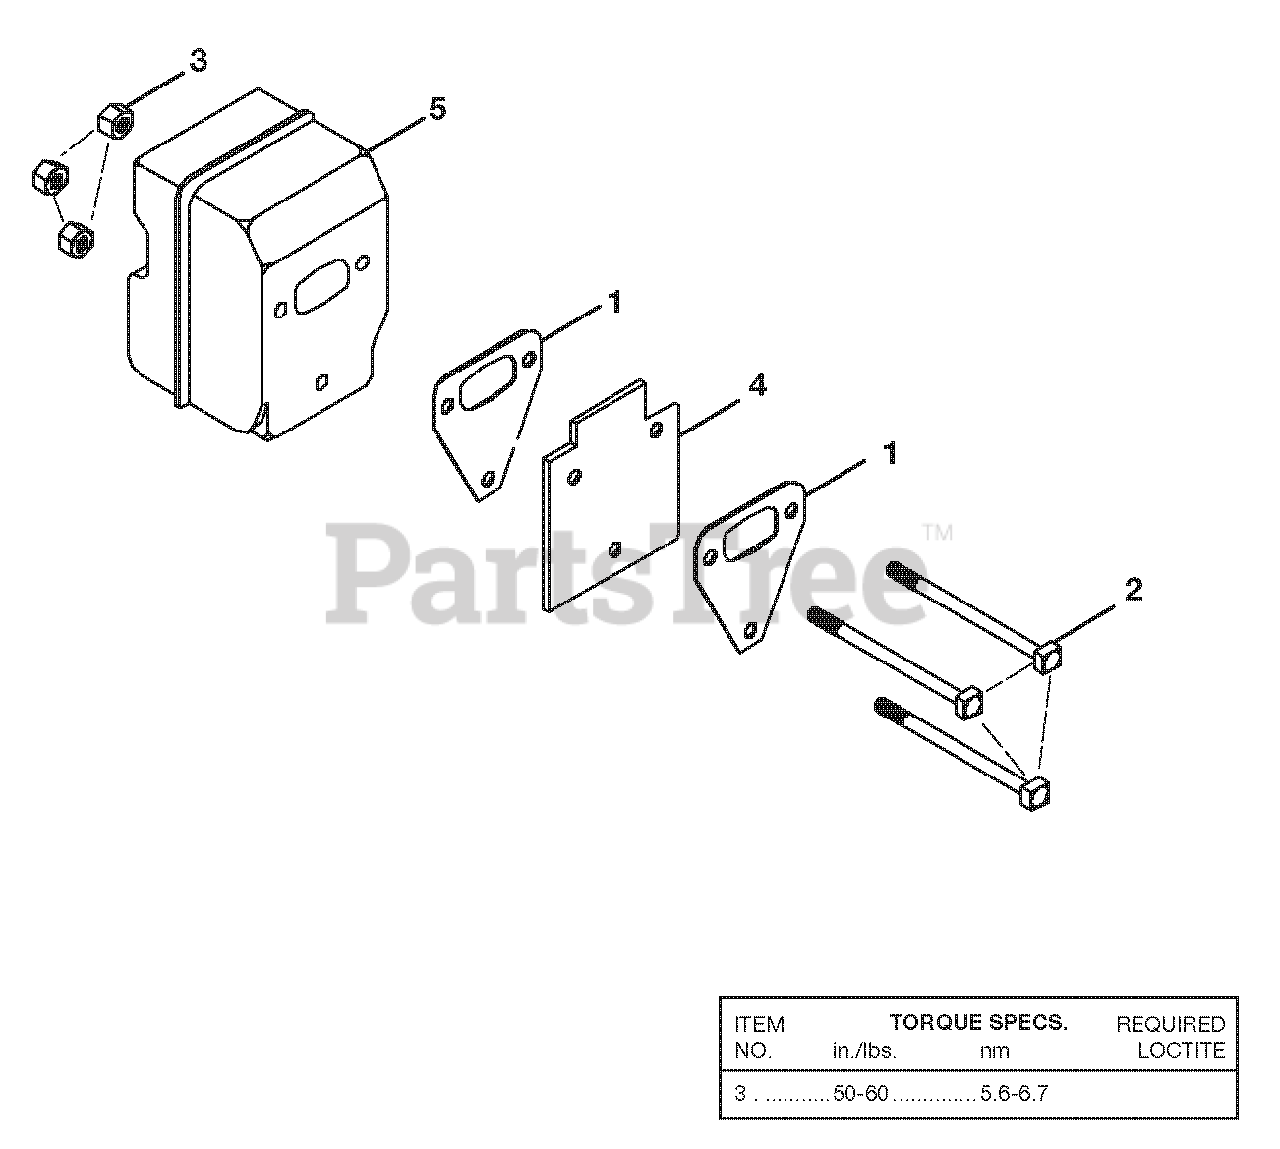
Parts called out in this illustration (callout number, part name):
1	MUFFLER GASKET
2	SCREW-SQUARE HD.
3	NUT-LOCKING HEX (10-32)
4	MUFFLER PLATE
5	MUFFLER ASSEMBLY
